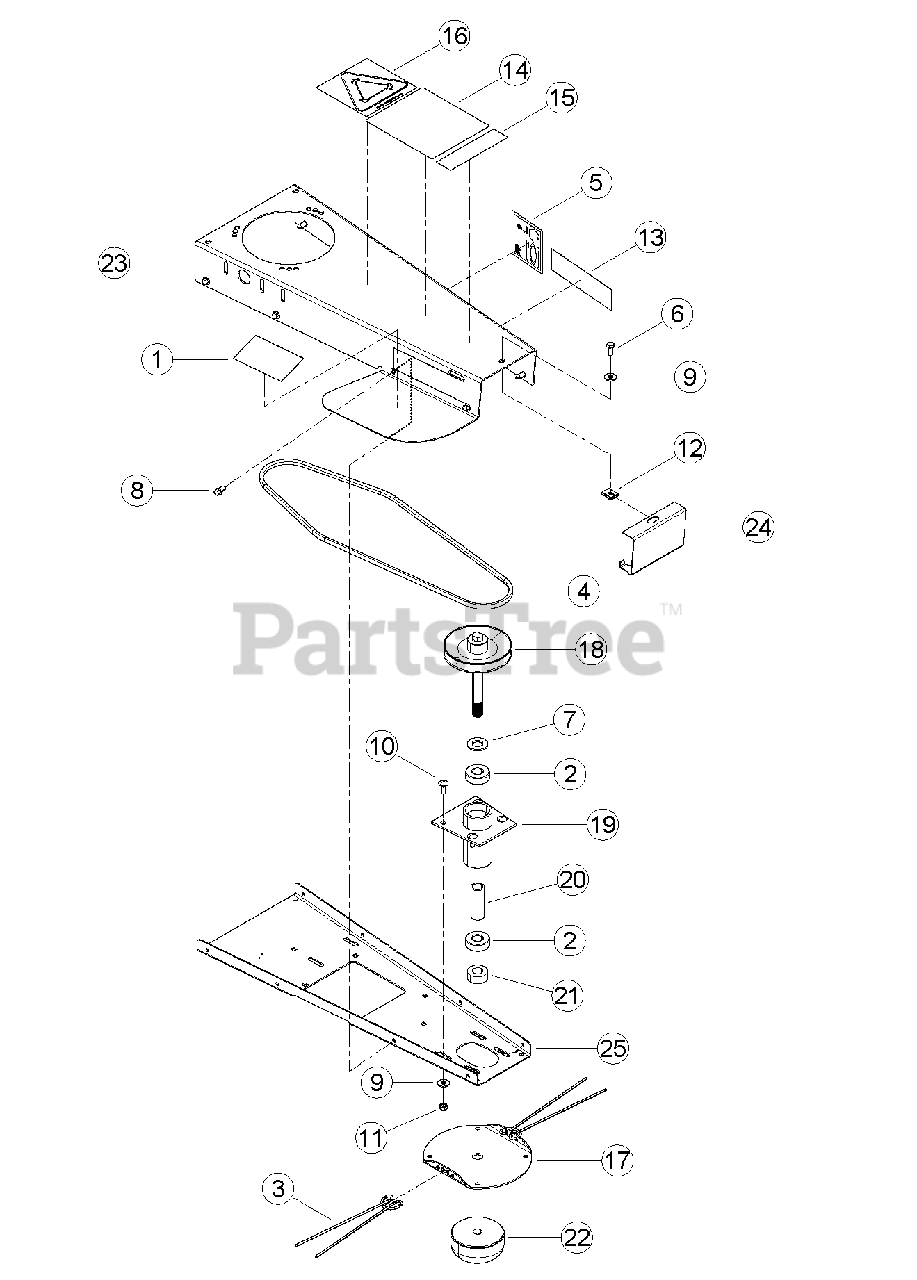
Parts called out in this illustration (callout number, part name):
1	DECAL, GRINDER DANGER
2	BEARING, 3/4 BALL
3	PLEASE SEE SERVICE PARTS & ACCESSORIES FOR REPLACEMENT OPTIONS
4	BELT, 3L X 52
5	DECAL, 101 DB (WT190S)
6	BOLT, 5/16 3/4 HEX HD GR5 ZP
7	WASHER, 3/4 SAE FLAT ZP
8	SCREW, 11/32 X 7/8 HWH AB THREAD ZP
9	WASHER, 5/16 FLAT ZP
10	BOLT, 5/16 X 7/8 CRG GR5 NC ZP
11	NUT, 5/16 NE NYLOCK ZP
12	NUT 5/16-18 TINNERMAN U-TYPE
13	DECAL, ECHO BEARCAT 6.82 X 1.90
14	DECAL, MANUAL/SAFETY INFO
15	DECAL, MODEL WT190S
16	DECAL, RECLAIM IT
17	DISK, TRIMMER HEAD
18	WELDMENT, TRIMMER PULLEY
19	WELDMENT, SPINDLE HUB
20	SPACER, TRIMMER SPINDLE
21	SPACER, TRIMMER HEAD
22	WELDMENT, TRIMMER HEAD USE 72704-12
23	BODY, TRIMMER
24	COVER, FRONT TRIMMER
25	BOTTOM, TRIMMER FRAME
